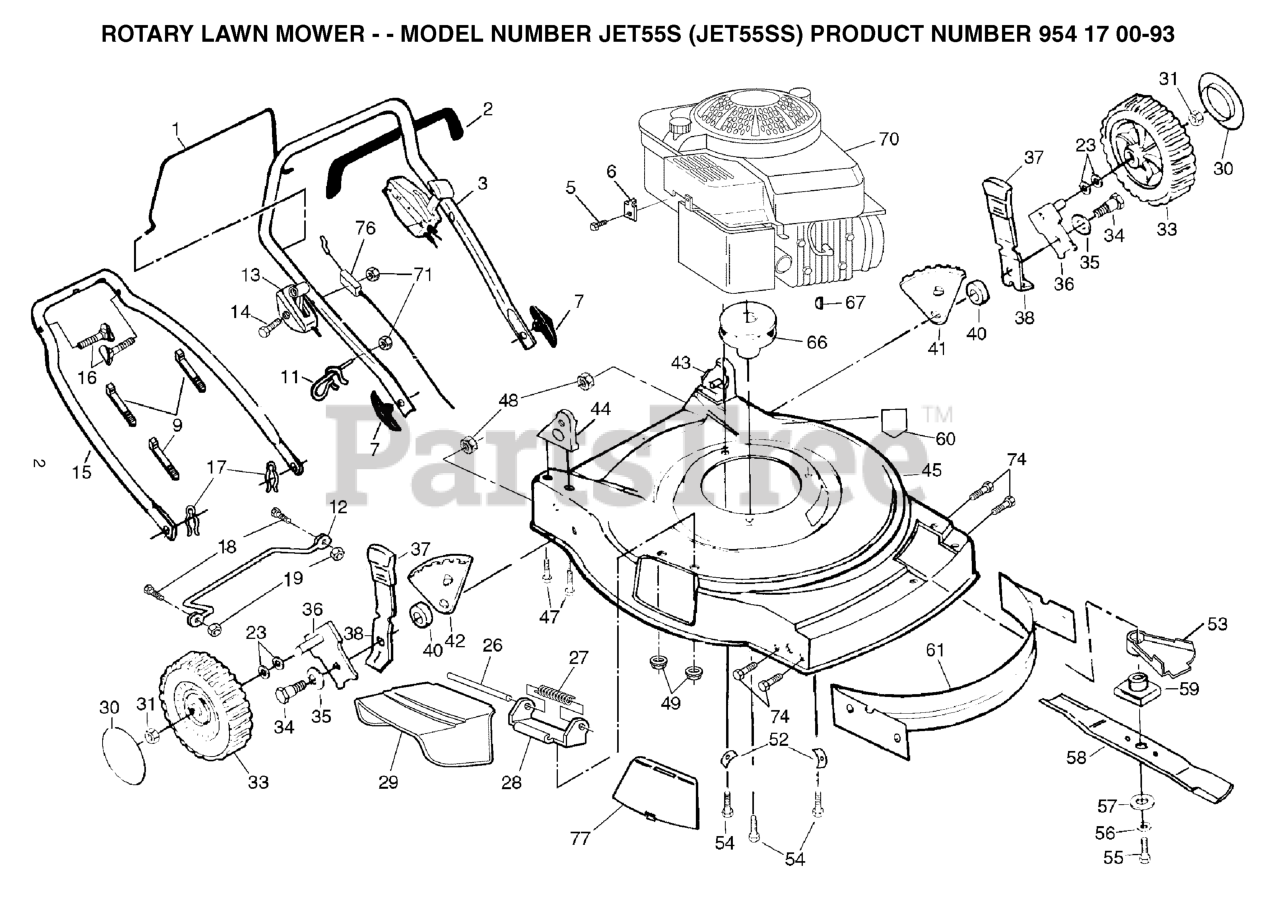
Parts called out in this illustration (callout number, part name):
1	BAIL.CNTRL.DLX.CK
2	GRIP.HANDLE.FOAM
3	HANDLE.UP.DLX.COMF.W/GRIP.GREY
5	SCREW.HEX.HEAD.WASHER.10-16
6	CABLE CLAMP(ENGINE)
7	HANDLE KNOB
9	TIE GUIDE
11	ROPE, GUIDE
13	CONTROL.THROTL.48.5.INTK.RT.HS
14	SCREW 1/4-20 X 2.12
15	LOWER HANDLE
16	HANDLE BOLT
17	HAIRPIN COTTER
18	REPL BY 817 02 10-08
23	WAVE WASHER
26	ROD.HINGE.COMBI-C
28	BRACKET PM
29	DISCHARGE GUARD
30	HUBCAP.8".GREY
31	HEX FLANGE LOCKNT
33	WHEEL.8X2.PR.LP.RAD.GREY
34	BOLT
35	WASHER.BELLEVILLE (3 2 LB)
36	AXLE ARM
37	SELECTOR KNOB
40	RP SPACER HT ADJ
41	WHL ADJ BRKT RF/LR
42	WHL ADJ BRKT LF/RR
43	HANDLE BRACKET ASM. LH
44	HANDLE BRACKET ASM. RH
47	SCREW.5/16-18X3/4
48	LOCKNUT PM
49	LOCKNUT.NYLOC.1/4-20
52	WASHER.ENGINE.BZP
53	SHIELD.DEBRIS.21.RWGD.EZ
54	BOLT 3/8-16X1-1/8
55	SCREW, HEX HD 3/8-24 X 1-3/8
56	LOCKWASHER
57	WASHER,HARDEN
59	BLADE ADAPTOR
60	DECAL.INTERNATIONL.CUTFINGER
66	ENGINE.PULLEY.FWG
67	HI PRO KEY PM WSL
71	NUT
74	SCREW 1/4X20
75	DECAL.INTRN.SELF-PROPELLED.02
76	ENGINE ZONE CONTROL CABLE
77	REPL BY 532 12 54-20
